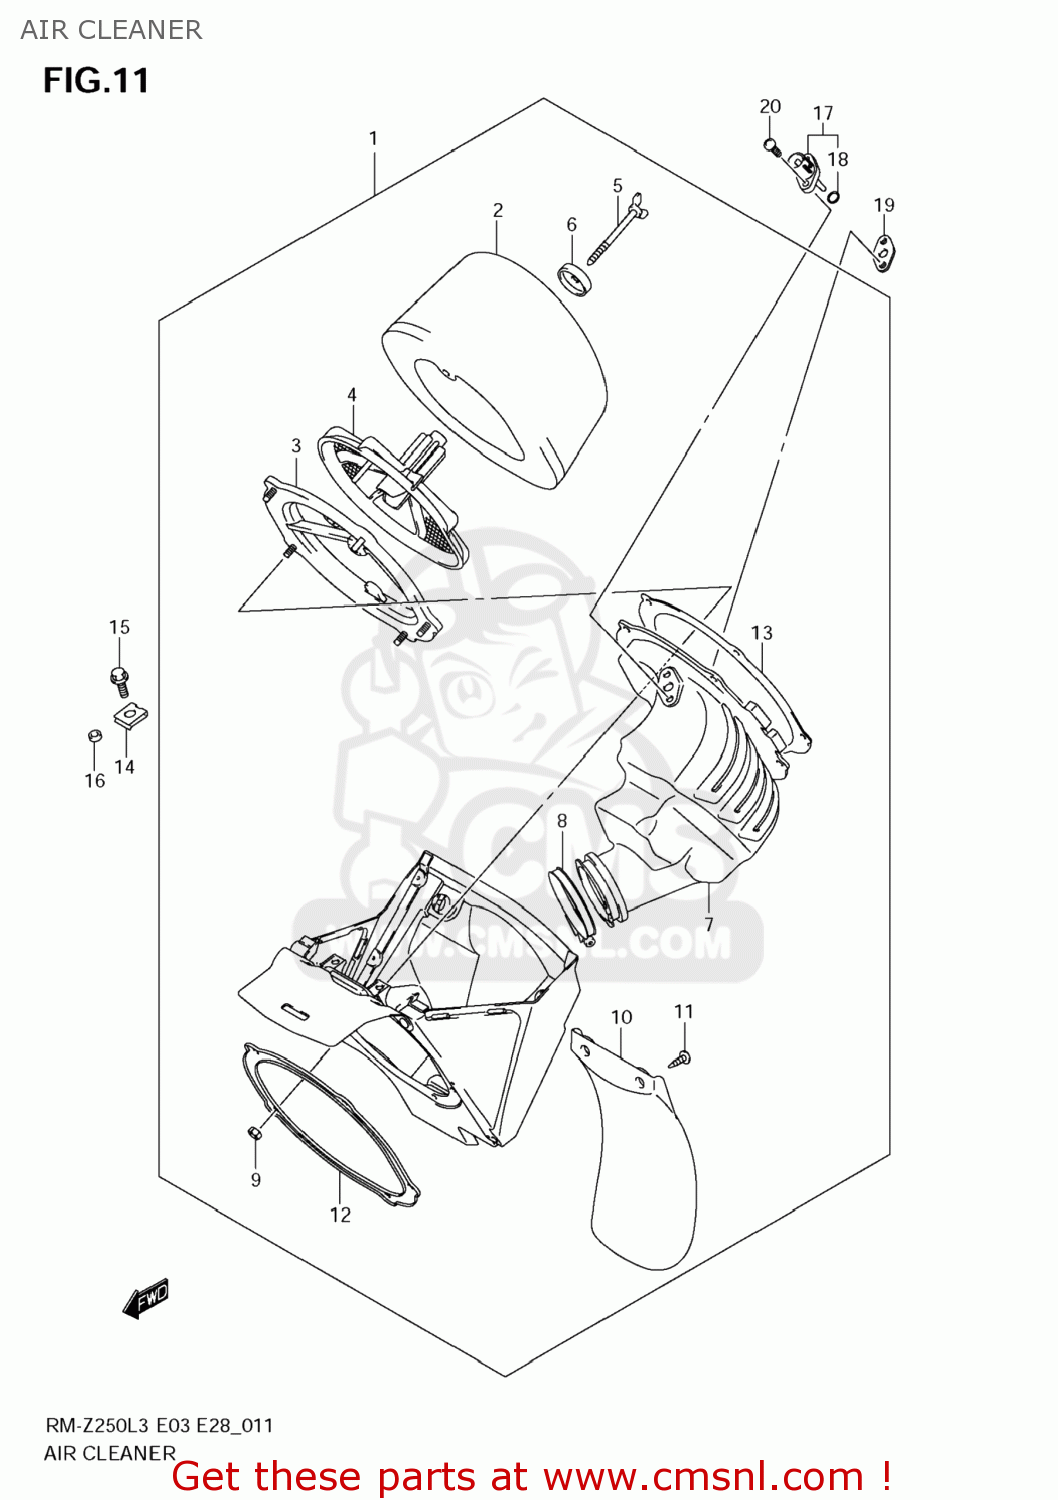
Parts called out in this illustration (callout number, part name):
1	CLEANER ASSY,AIR
2	FILTER ASSY
3	BASE,FILTER
4	HOLDER,FILTER
5	BOLT,WING
6	WASHER,AIR CLEANER
7	TUBE,OUTLET
8	CLAMP,AIR CLEANER
9	NUT
10	MUDGUARD
11	SCREW
12	PLATE
13	GASKET (NAS)
14	NUT
15	BOLT
16	SPACER(6.2X10X2.2)
17	SENSOR,AIR TEMP
18	O RING
19	BRACKET,AIR TEMP SENSOR
20	SCREW
